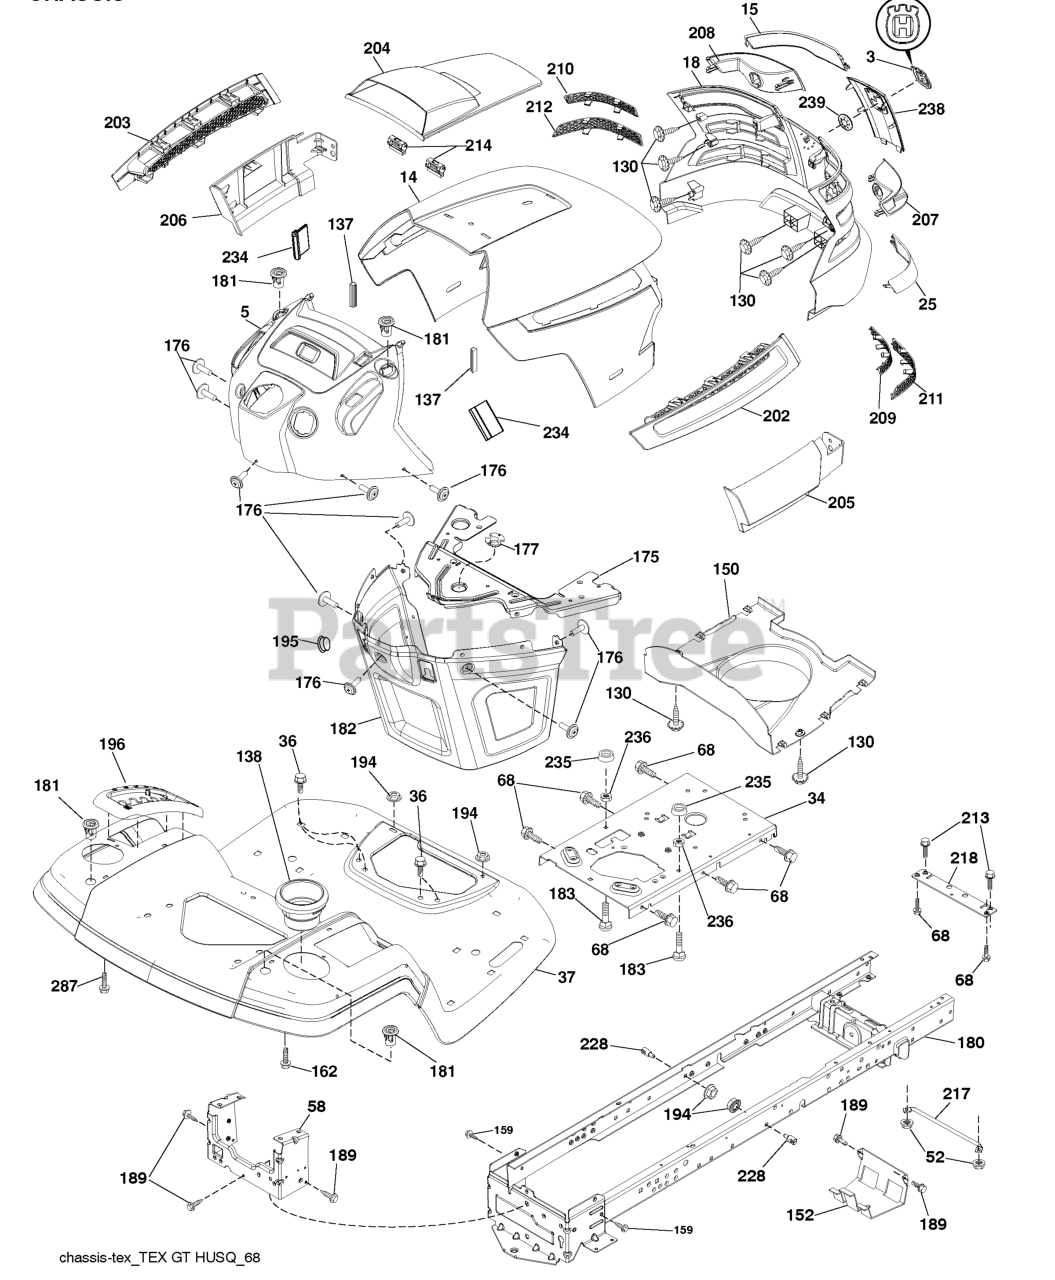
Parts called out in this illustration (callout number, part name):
3	LOGO.HUSQ.GT.LT.CROWN.H
14	HOOD
15	LENS.LH.TEX.GT.HUSQ.CL
18	GRILL.ASM.HUSQ.TG/CRD.W/TRIM
25	LENS.RH.TEX.GT.HUSQ.CL
34	PLATE.ENGINE.WELDED.CHASSIS
36	SCREW 5/16"
37	FENDER
52	LOCKNUT
58	DRAWBAR UPPER 2PC SMALL FENDER
68	Screw Thdrol 5/16-18 x 1/2
130	SCREW.#10 X 0.750.BOS
137	BUMPER DASH
138	CUPHOLDER.TL.TEX.418
150	AIR.DUCT.HOOD.TEX.GT.HUSQ
152	SHIELD.BROWNING.W/TEX
159	SCREW, 3/8-16X3/4
162	SCREW.HI-LO.CONSOLE
175	PLATE.CROSSMEMBER.HUSQ
176	SCREW.#10-24X5/8.RN.QU
177	BUSHING, STEERING
180	CHASS.WLDMNT.TL.12GA/2P.48/54
181	BUSHING.MNT.FEND.CRGO.
182	DASH.LOWER.COMMON.12V.ADAPTOR
183	BOLT.5/16-18X1-1/4 FULL THD
189	SCREW
194	NUT LOCK HEX FLANGE 5/16-18
195	PLUG.HOLE.DASH.LOWER.12V.BLK
196	RP CONSOLE.ASM.DECKLFT.GR/RBT.
202	VENT.SIDE.HOOD.HUSQ.RH.GREY
203	VENT.SIDE.HOOD.HUSQ.LH.GRAY
204	HOOD VENT
205	SKIRT.HOOD.SIDE.HUSQ.RH.GREY
206	SKIRT.HOOD.SIDE.HUSQ.LH.GREY
207	BEZEL.RH.TEX.GT.HUSQ
208	BEZEL.LH.TEX.GT.HUSQ
209	INSERT.HEX.GRILL.HUSQ.GREY
210	INSERT.HEX.GRILL.HUSQ.
211	INSERT.HEX.GRILL.HUSQ.
212	INSERT.HEX.GRILL.HUSQ.
213	BOLT
214	CLIP.RETAINER.TINNER.
217	ROD.PIVOT.HOOD
218	X-PIECE.HOOD.STOP.NON/
228	STUD.FASTNER.W/ANTI-ROTATE
234	BUMPER.HOOD.TEX.HUSQVARNA
235	SPACER FENDER
236	NUT.CENTERLOCK.5/16-
238	TRIM.HUSQ.TG/CRD.SERVICE
239	NUT PUSH M
287	SCREW 1/4X20
